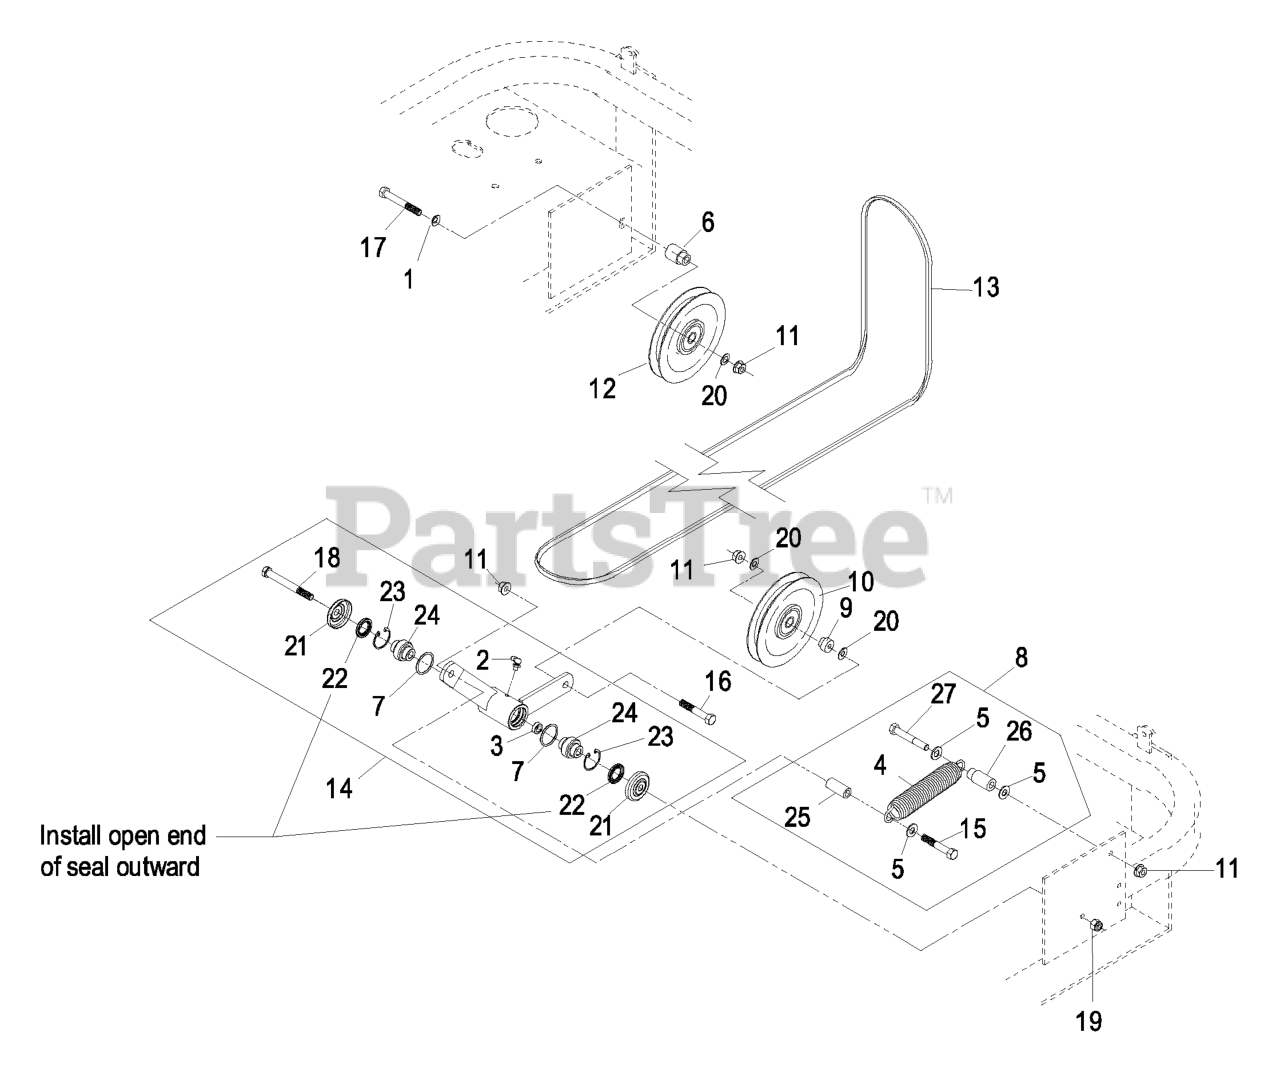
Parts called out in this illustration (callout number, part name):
1	WASHER-BELLEVILLE
2	FITTING-GREASE, 90 DEG
5	WASHER-FLAT
6	BUSHING-IDLER
9	BUSHING-IDLER
10	PULLEY-IDLER
11	NUT-HHF, WHIZ
12	PULLEY-IDLER
13	BELT,B 116.1"
14	KIT,MULE IDLER LZ
15	SCREW-HH
16	SCREW-HH
17	SCREW-HH
18	SCREW-HH
19	NUT-LOCK, NI
20	WASHER-FLAT
21	GUARD-TOP
22	SEAL-LIP, SINGLE
23	RING-SNAP
24	BEARING-SPHERICAL
25	BUSHING-LEVER, LIFT
27	BOLT-CARR
